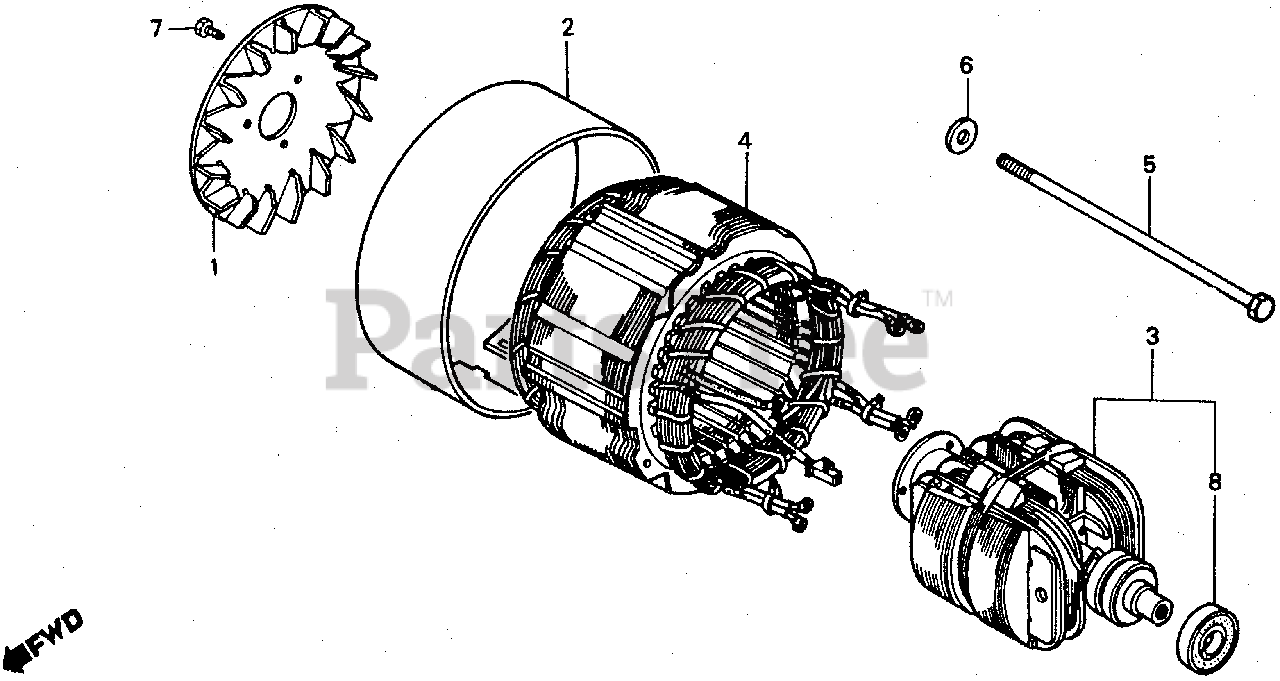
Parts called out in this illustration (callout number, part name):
2	COVER, STATOR *R8* (BRIGHT RED)
3	ROTOR
4	STATOR ASSY.
5	BOLT, HEX. (10X270)
6	WASHER, PLAIN (10MM)
7	SCREW, TAPPING (5X14)
7	SCREW-WASHER (5X10)
8	BEARING, RADIAL BALL (6205UU)
